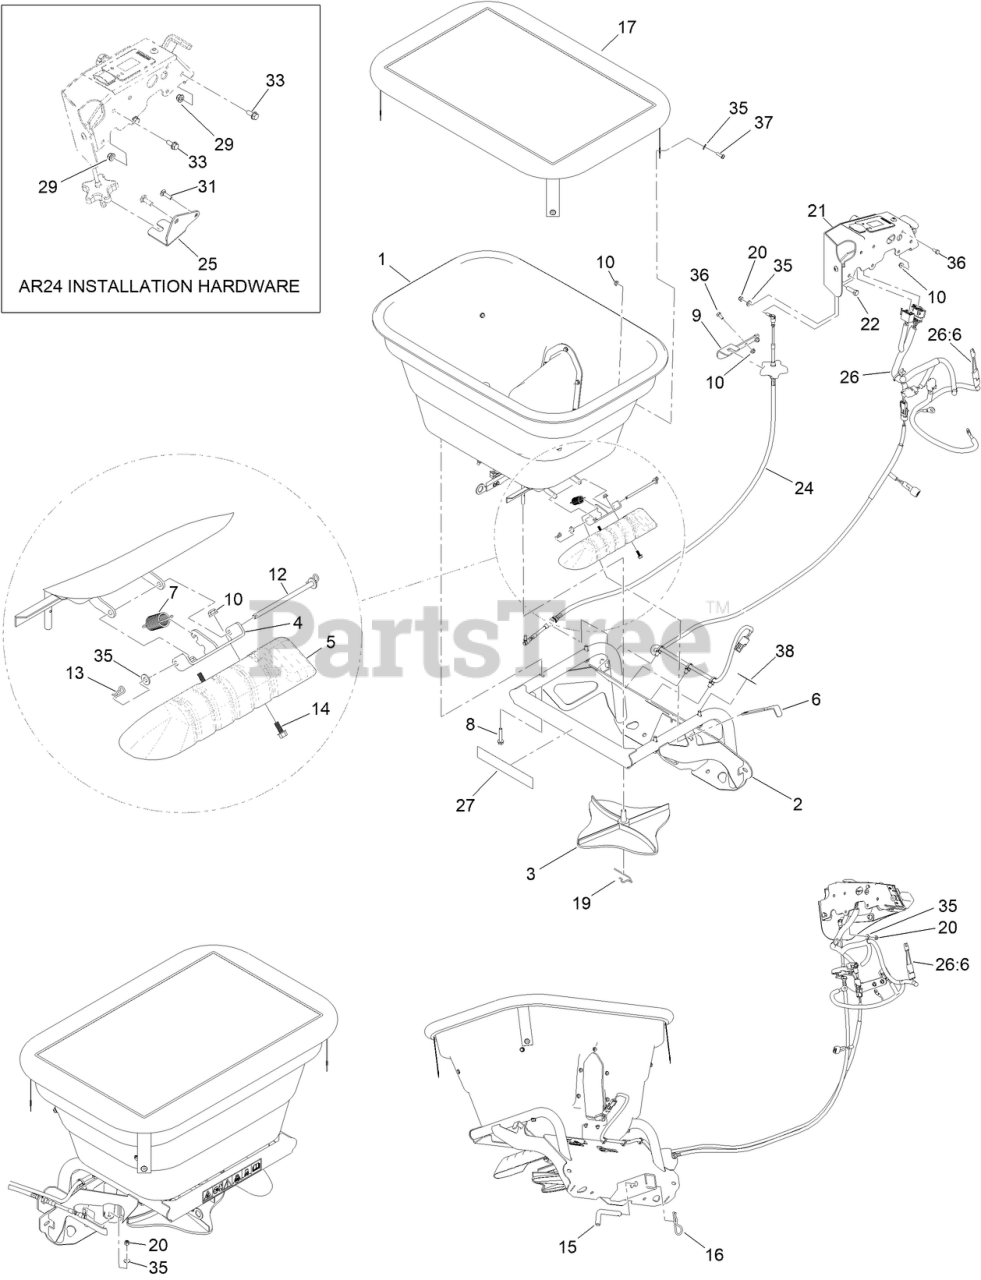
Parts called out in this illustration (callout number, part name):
1	SPREADER HOPPER ASM
2	SPREADER HOPPER FRAME ASM
3	SPINNER-SPREADER
4	BRACKET-DEFLECTOR
5	DEFLECTOR
6	STRAP-ENGAGEMENT
7	SPRING-EXTENSION
8	SCREW-HWH
9	BRACKET-CABLE
10	NUT-HF
12	PIN-PIVOT
13	PIN-COTTER
14	SCREW-HHF
15	PIN-HITCH
16	PIN-HAIR
17	COVER-HOPPER
19	CLIP-SPINNER
20	NUT-LOCK
21	SPREADER CONTROLLER ASM
22	SCREW-HH
24	CABLE-PUSH, PULL
25	BRACKET-CABLE
26	HARNESS
26:6	CONNECTOR
27	DECAL-DOWN, TIE
29	NUT-HF, NI
31	SCREW-CARR
33	SCREW-HHF
35	WASHER-FLAT
36	SCREW-HH
37	SCREW-HWH
38	DECAL-WARNING
